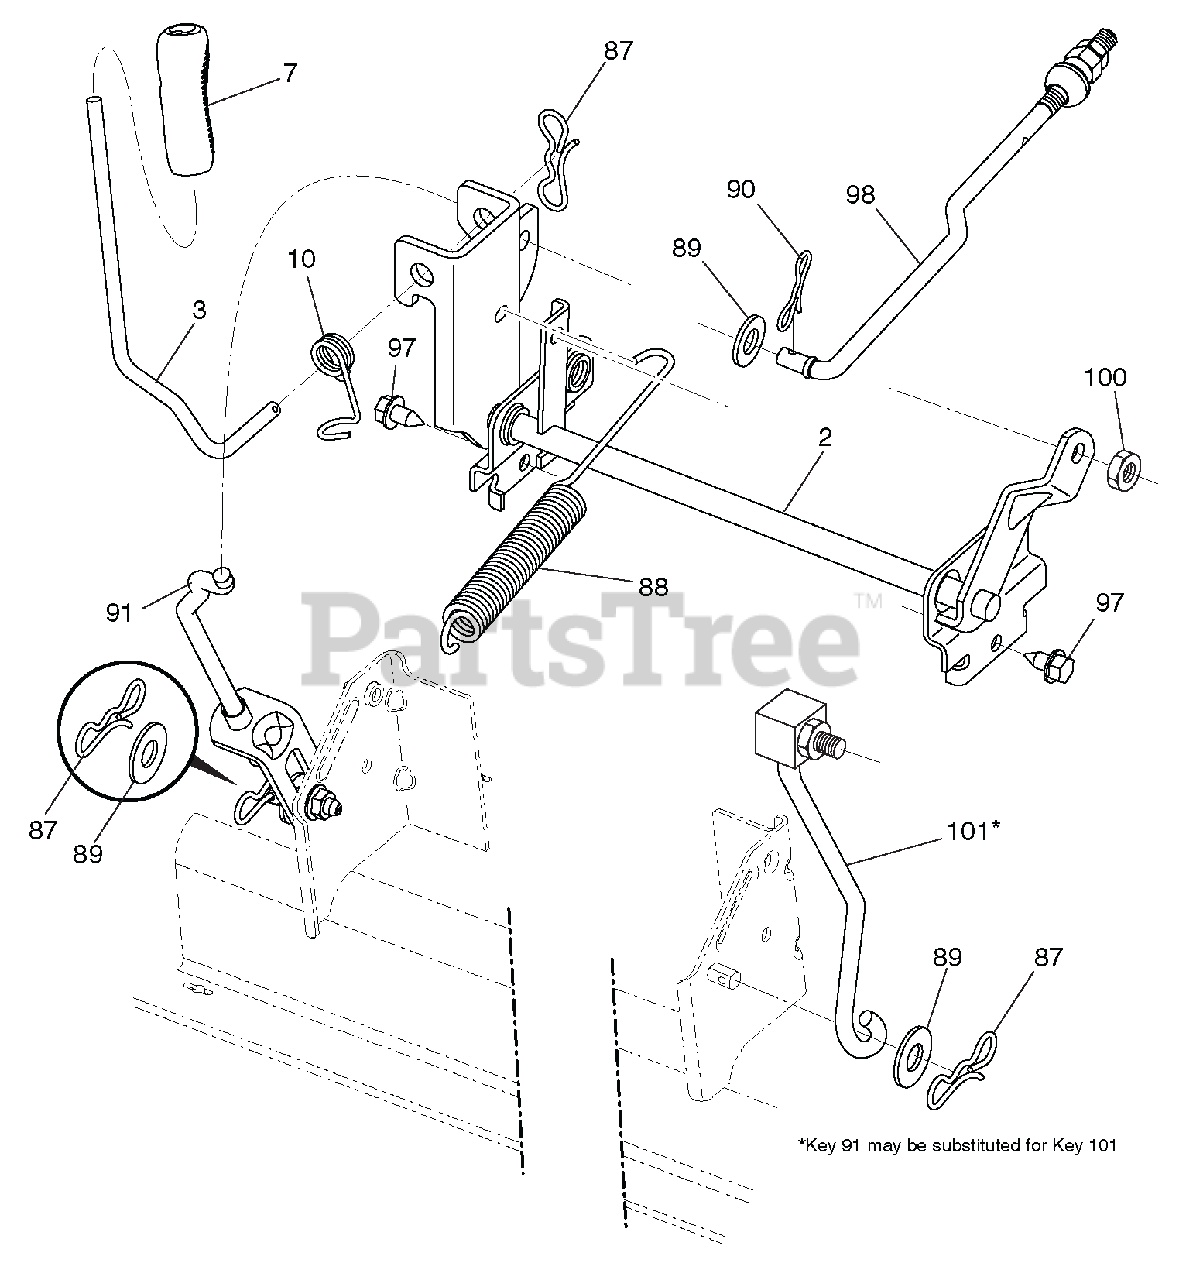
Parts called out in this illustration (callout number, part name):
2	SHAFT ASM., LIFT
3	LEVER.LIFT.HANDLE.LT
7	GRIP LEVER 5625 LD BLACK 428
10	SPRING.TORSION.HANDLE.LIFT
87	PIN.COTTER.7/16.BOW TIE LOCK
88	SPRING.LIFT ASSIST
89	WASHER.CLEAR ZINC
90	PIN.COTTER.5/16.BOW TIE LOCK
91	LINK ASM.LIFT.LH.REAR
97	SCREW.HEXWSH THDR3/8-16X3/4.BL
98	LINK ASM.SUSP.FRONT.MWR.11
100	NUT.CENTERLOCK.3/8-16 UNC.
101	LINK ASM.LIFT.FIXED.38/42/46"
